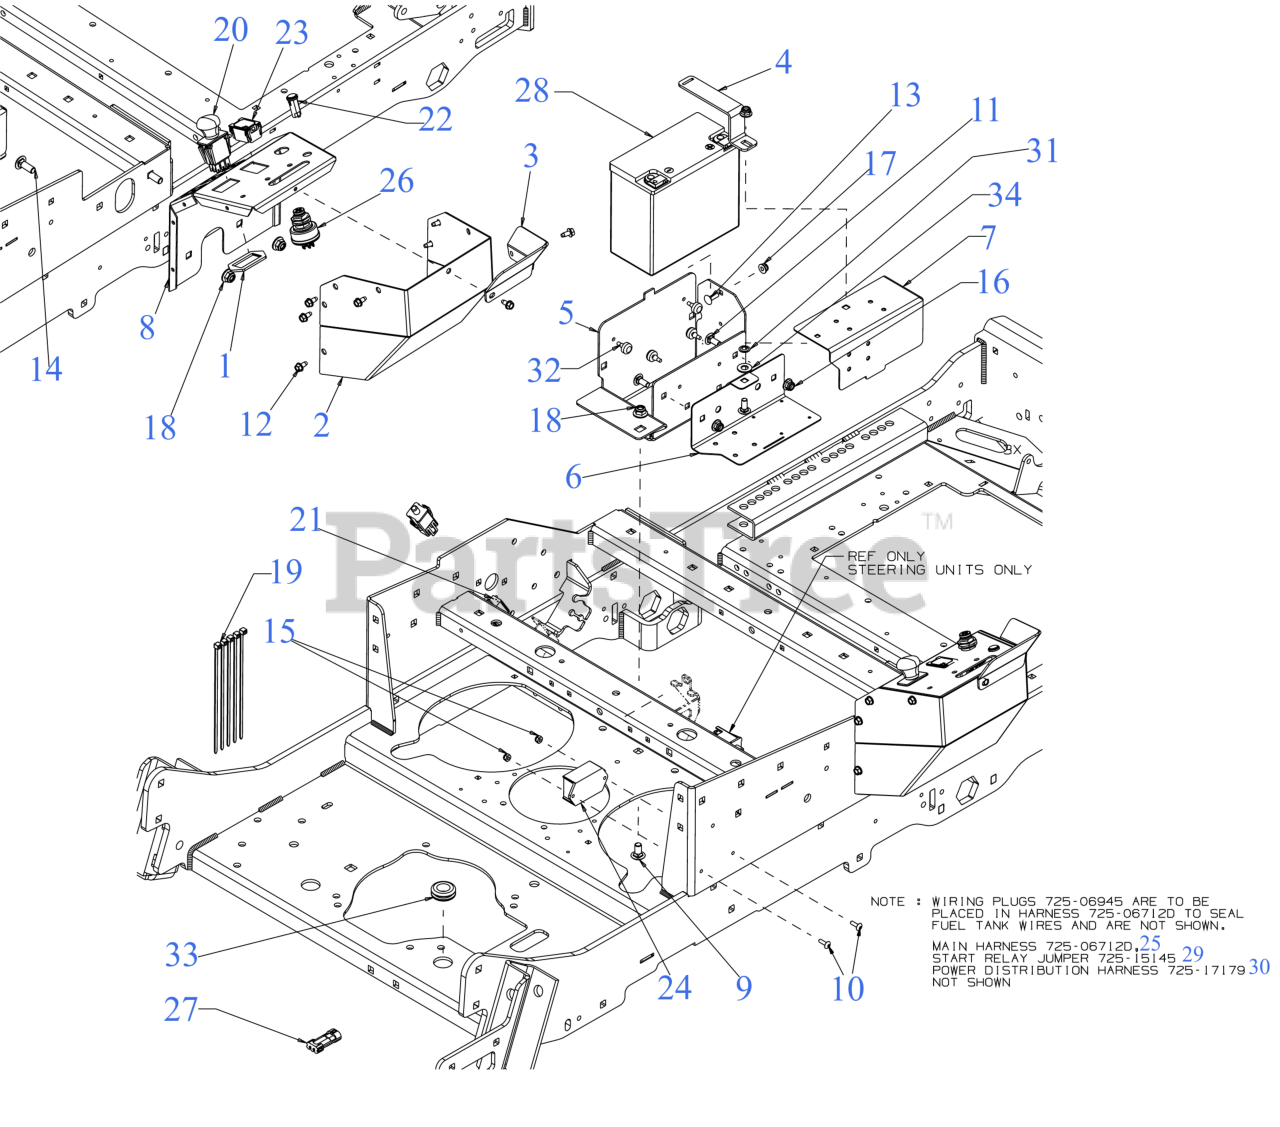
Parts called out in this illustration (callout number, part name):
1	BRACKET-PTO SWITCH
4	BATTERY SUPPORT BRACKET
5	BATTERY MOUNT BRACKET
6	MOUNT BRACKET (LOWER)
7	COVER BRACKET (UPPER)
8	CONTROL POD (RH)
9	CARRIAGE BOLT 3/8-16 x .750 GR5
10	SCREW #10-24 x .62
11	CARRIAGE BOLT 5/16-18 x .75
12	SCREW 1/4-20 X.500
13	SCREW 1/4-20 x .75 GR5
14	CARRIAGE BOLT 3/8-16 x 1.00 GR5
16	FLANGE LOCK NUT 5/16-18
17	FLANGE LOCK NUT
19	7" CABLE TIE
20	PTO SWITCH (BLACK KNOB) TEXT SYM
21	3 POLE SWITCH ( NC-NO-NO)
22	INDICATOR LIGHT-RED
24	CONTROL PANEL (SOFT CLUTCH)
25	WIRE HARNESS ASSEMBLY (KOH/KAW EFI)
26	KEY SWITCH (3 POSITION)
26	PRO-Z KEY SET
27	SEALED CAP ASSEMBLY
28	BATTERY (300 CCA)
29	JUMPER HARNESS (W/RELAY)
30	AUX POWER HARNESS
32	BUMPER, .62 DIA x .3
33	RUBBER GROMMET
34	FLAT WASHER
